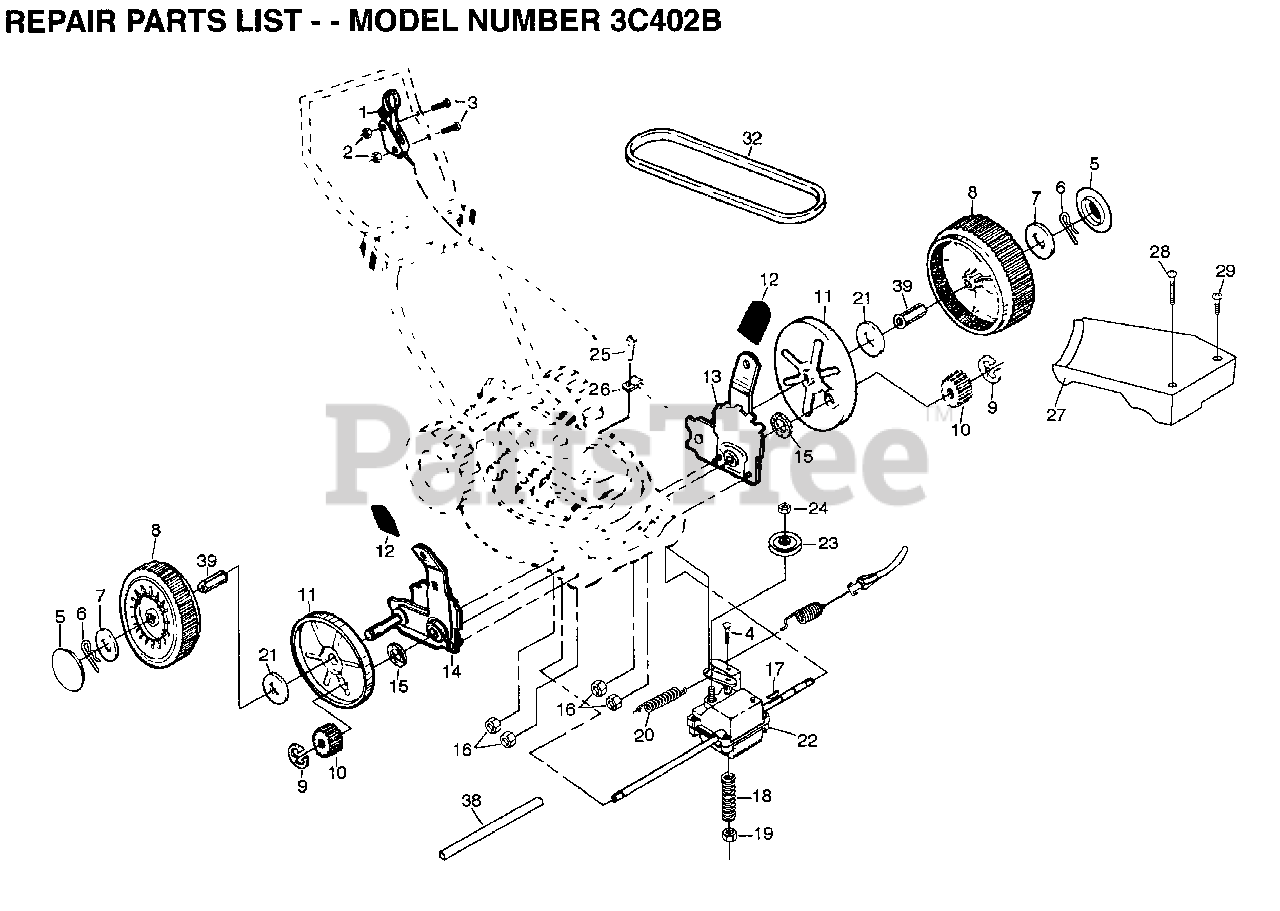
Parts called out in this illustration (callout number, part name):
1	CONTROL.DRIVE
3	SCREW
4	BOLT.1/4-20X2.0
5	HUB CAP
6	RETAINER CLIP PM
7	WASHER
8	WHEEL.8X2.LP.PR
10	PINION.GEAR
11	DUST SHROUD PM
12	KNOB PM
15	WASHER PM
17	HI PRO KEY
18	SPRING.TENSION
20	SPRING
21	WASHER FLUT
23	PULLEY.DRIVEN
24	LOCKNUT
25	TAPPING SCREW
26	GUIDE CLIP PM
27	COVER DRIVE BLK
38	DRV SHAFT TUBE PM
39	BUSHING.HEX
